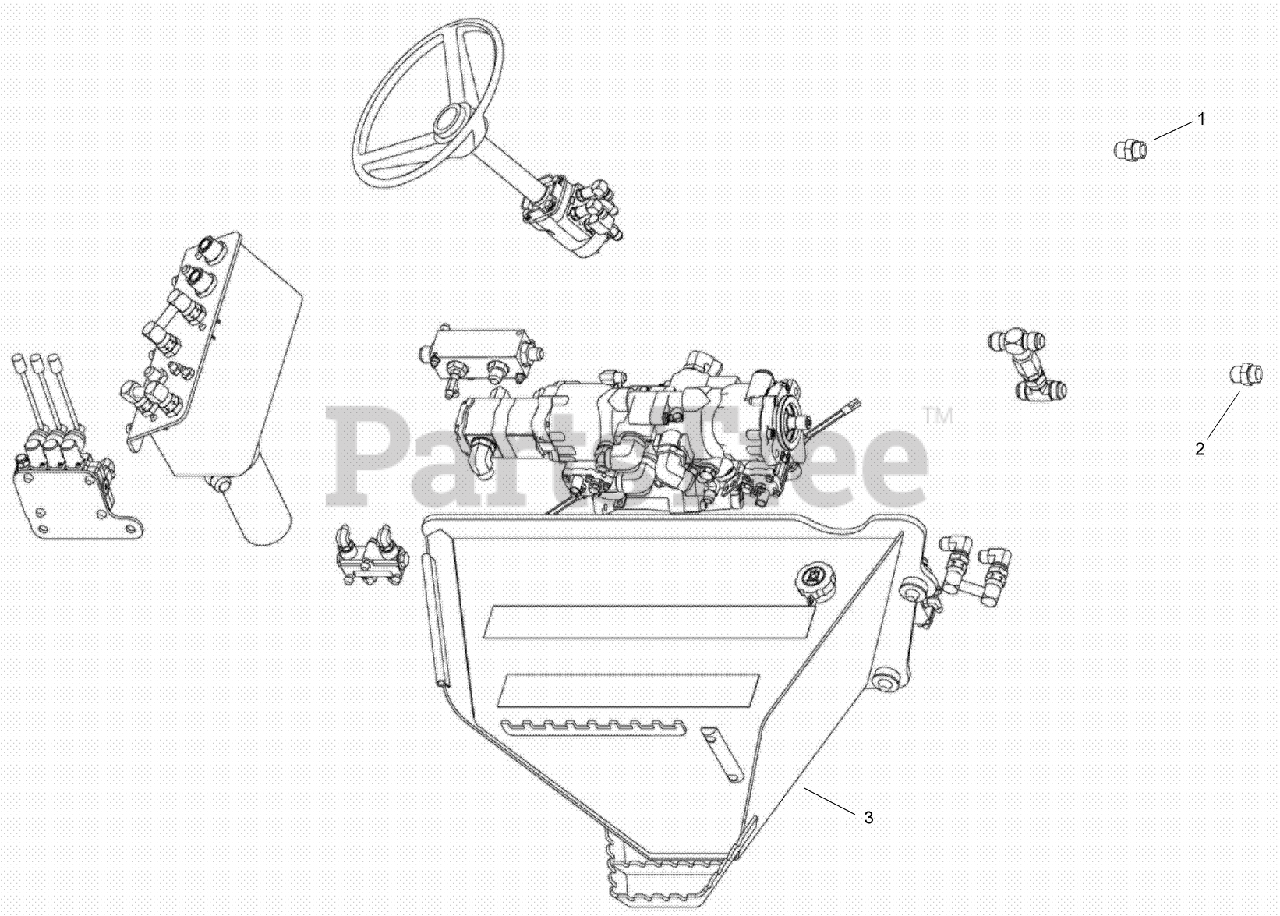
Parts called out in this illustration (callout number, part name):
1	FITTING-STRAIGHT
2	FITTING-STRAIGHT
3	ASM-Hydraulic Tank
